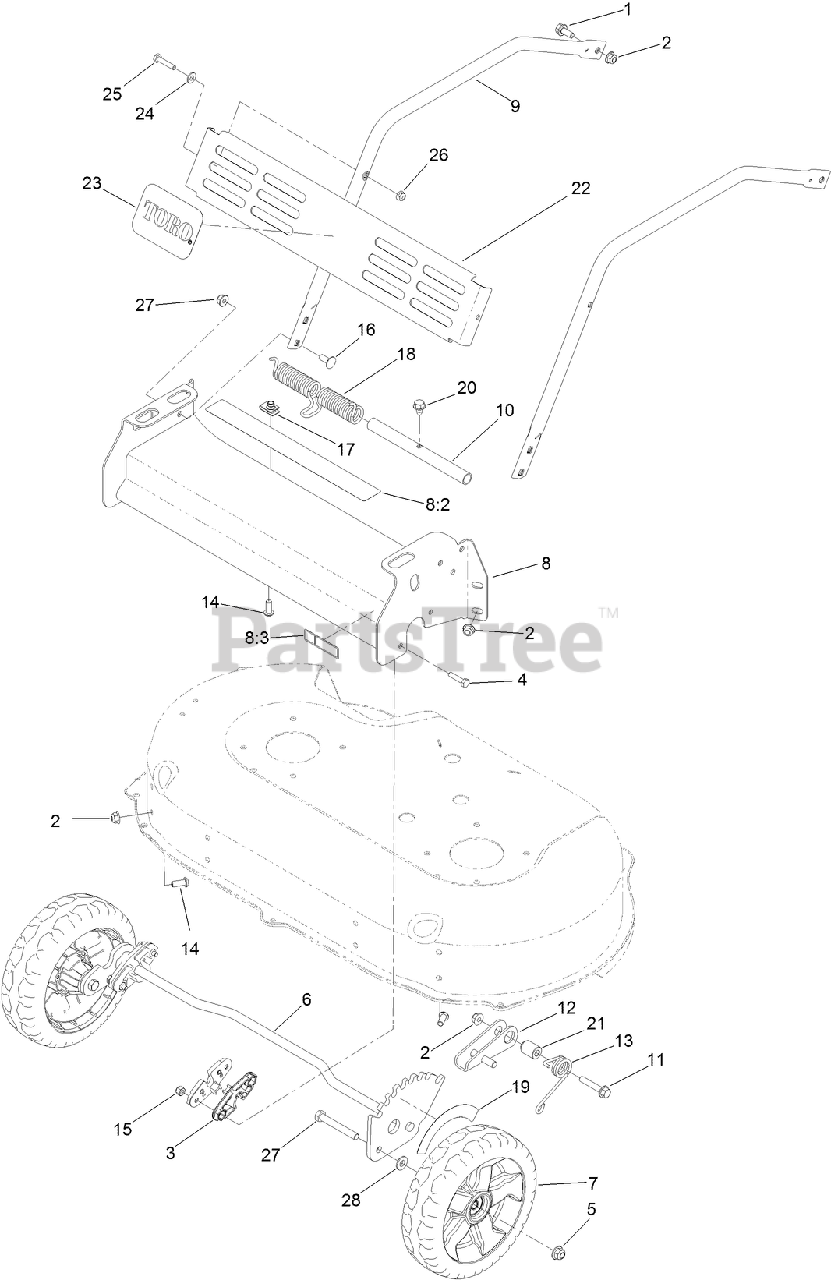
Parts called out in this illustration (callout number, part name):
1	SCREW-HHF
2	NUT-HF, NI
3	BUSHING-FRONT
4	SCREW-HH
5	NUT-HF, NI
6	AXLE-FRONT
7	WHEEL
8	FRONT BUMPER ASM
8:3	DECAL-WARNING
10	MANDRELL-SPRING
11	SCREW-HWH
12	LOCK-HEIGHT, ADJUSTMENT
13	SPRING-TORSION
14	SCREW-HSBH
15	NUT-LOCK, NI
16	SCREW-CARR
17	NUT-U
18	SPRING-TORSION
19	DECAL-HOC, FRONT
20	SCREW
21	SPACER
24	WASHER-FLAT
25	SCREW-HH
26	NUT-HF
27	SCREW-HH
28	SPACER-COVER, WHEEL
